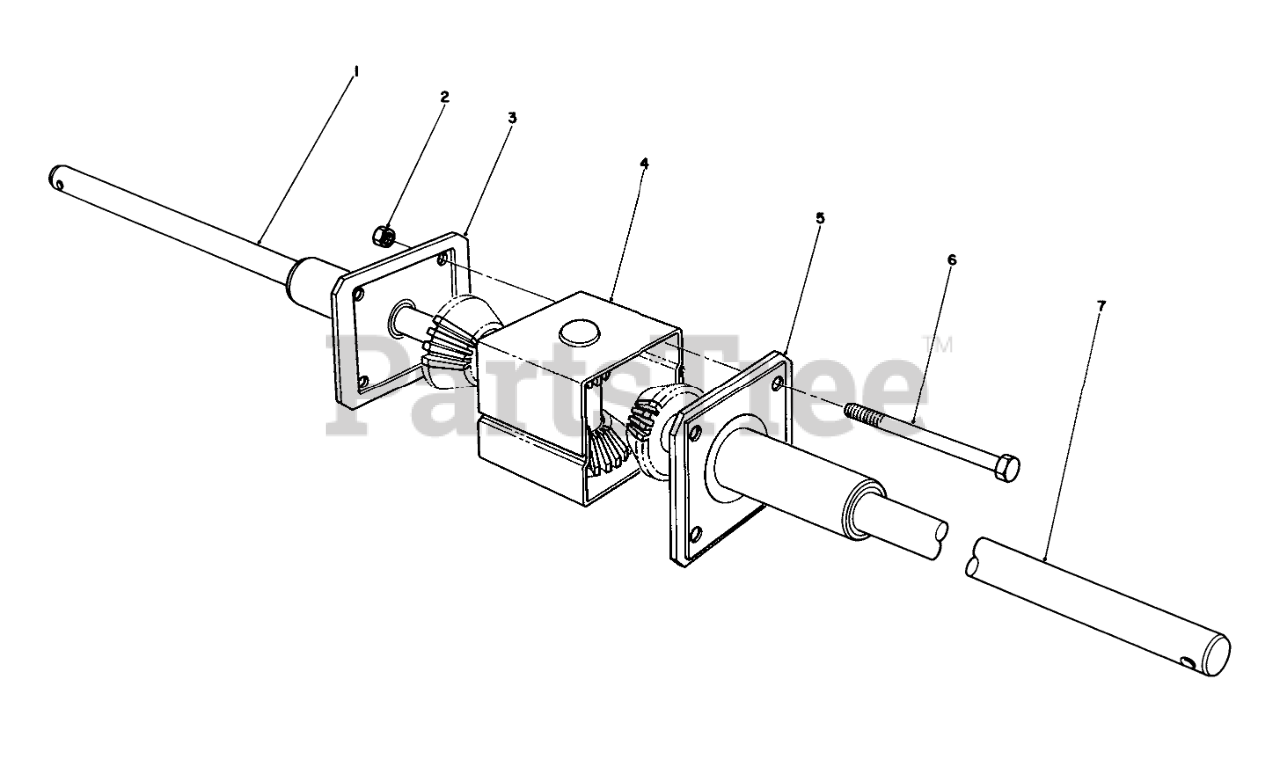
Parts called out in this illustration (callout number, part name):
1	Axle-R.H.
2	NUT-LOCK, CONE
3	END CAP/BRG ASM
4	GEAR CASE ASM
5	END CAP &BEARING ASY
6	SCREW-HH
